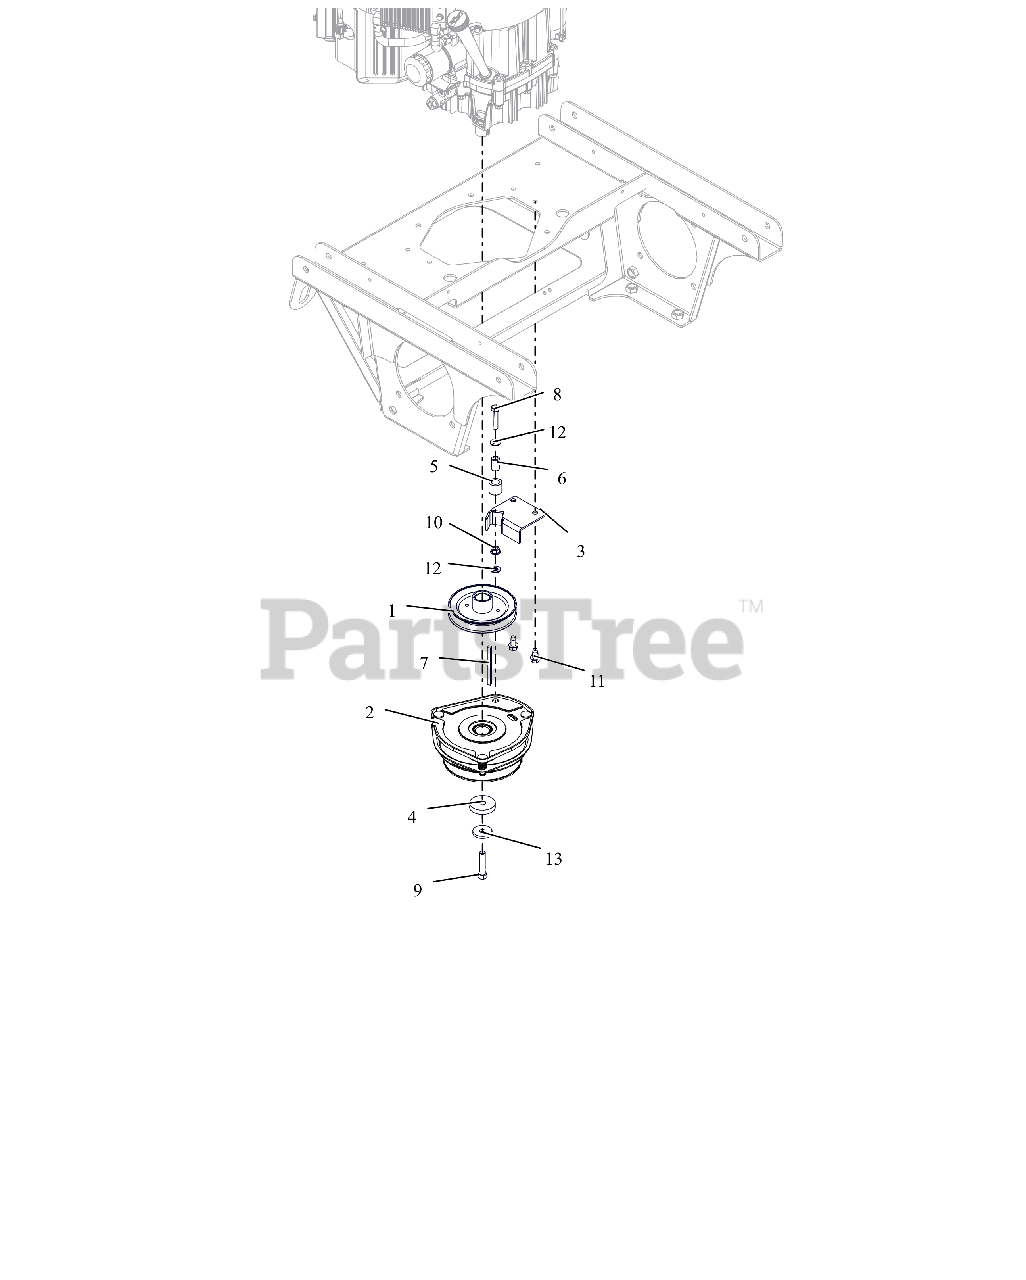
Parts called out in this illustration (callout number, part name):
1	SHEAVE-ENGINE 1.127ID X 5.25OD
2	CLUTCH, ELE-OGURA GT3.5-VP01R
3	CLUTCH STOP WLDMT - BLACK
4	SPACER, .450X2.00X.396
5	BUMPER,RUBBER .62X1.0X.88 LG
6	BUSH.,S.391X.622X.950 ST
7	KEY-SQ. .25X3.50X.25 SAE
8	BLT, HEX .38-16X1.75 G5 ZCC
9	BLT, HEX 0.4375-20X2 G8 ZCC NT
10	NUT-LK-TOP-FLG .38-16 ZC120
11	SCR,TAP .375-16X.75 HWH TR ZCC
12	WSHR,FLT .406X.812X.065 ZCC
13	WASHER, 7/16" SPRING DISK
